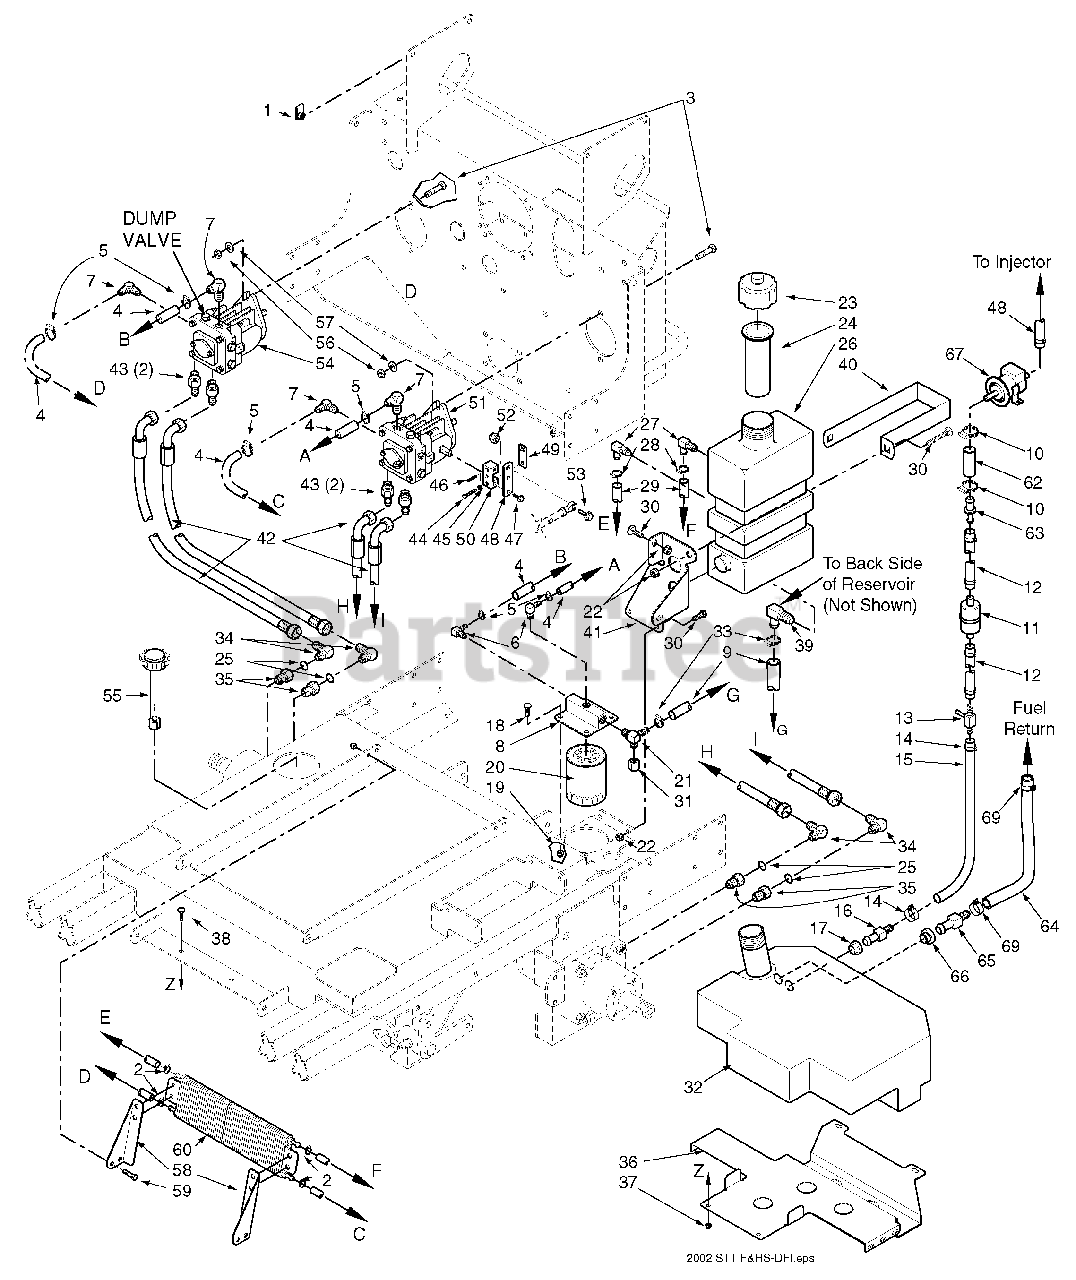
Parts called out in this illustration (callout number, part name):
1	U-Nut 1/4-20
2	Hose Clamp, 0.69" Dia.
3	Bolt, Hex Head 1/4-20 x 2.0"
4	Hose, 3/8" ID Pushlock
5	Clamp, Hose 1/2"
6	Elbow, 90 Degree - 1/4" NPT x 3/8" Hose
7	Elbow, 90 Degree - 9/16" O-Ring x 3/8" Hose
8	Oil Filter Base
9	Hose Assembly, 1/2" ID (Tank to Filter Base)
10	Clamp, .87" max Dia.
12	Fuel Hose, 5/16" ID. Non-Perm.
13	Valve, Shutoff Kawasaki
14	Clamp, Fuel Hose 5/13" Hose I.D.
15	Fuel Hose, 5/16" ID. Non-Perm.
16	Hose Fitting w/Screen
17	Bushing
18	Bolt, Hex Head 5/16-18 x1.0" Zinc
19	Nut, Serrated Flange 5/16-18
20	Oil Filter
21	Tee, 3/4" O-Ring x JIC x 1/2" Hose
22	Nut, Hex Elastic Stop 1/4-20
23	Cap, Hydraulic Tank
24	Insert, Filler Neck
25	O-Ring
26	Oil Reservoir Assembly
27	Elbow, 90 Degree .38" Hose
28	Hose Clamp, 0.69" dia.
29	Hose, 3/8" ID, Pushlock
30	Screw, Phillips Head, 1/4-20
32	Fuel Tank Assembly
33	Clamp, Hose
34	Elbow, 90 Degree, 7/8"-14 THD
35	Bushing, 7/8"-14 JIC x 3/4"-16 O-Ring
36	Support Bracket, Fuel Tank
37	Nut, 5/16-18 Serrated Flange
38	Bolt, Carraige 1/4-20 x 3/4"
39	Elbow, 90 Degree
40	Strap, Hydraulic Tank
41	Support Bracket, Hydraulic Tank
42	Hose Assembly, Pump
43	Union, 3/4"-16 JIC x 3/4"-16 O-Ring
44	Bolt, Hex Head, 1/4-20 x 1-1/4"
45	Lockwasher, 1/4" Spring
46	Roll Pin, Spring 3/16 x 3/4"
47	Bolt, Hex Serrated Flange, 1/4-20 x 3/4"
48	Fuel Hose, 5/16" ID.
49	Clamp Plate, Pump Control
50	Block, Pump Control
51	Pump, Left Hand, BDP-16A
52	Nut, Hex, Elastic Stop 3/8-16
53	Bolt, Hex Head, 3/8-16 x 1-1/4"
54	Pump, Right Hand, BDP 16A
55	Cap, Fuel Tank W/Gauge
56	Nut, Hex Elastic Stop 3/8-16
57	Flatwasher, 3/8" (.391 x .938 x .105") Grade 8
58	Mounting Bracket - LH, Oil Cooler
59	Bolt, Hex Head 5/16-18 x 3/4"
60	Cooler, Oil
61	Clamp, .69" Dia.
62	Hose, Fuel Line
64	Hose, 1/4" Fuel Line Non-Perm.
65	Fitting, Hose
66	Bushing
68	Fuel Hose, 5/16" ID. Non-Perm.
69	Clamp, Fuel Hose 1/4" Hose I.D.
